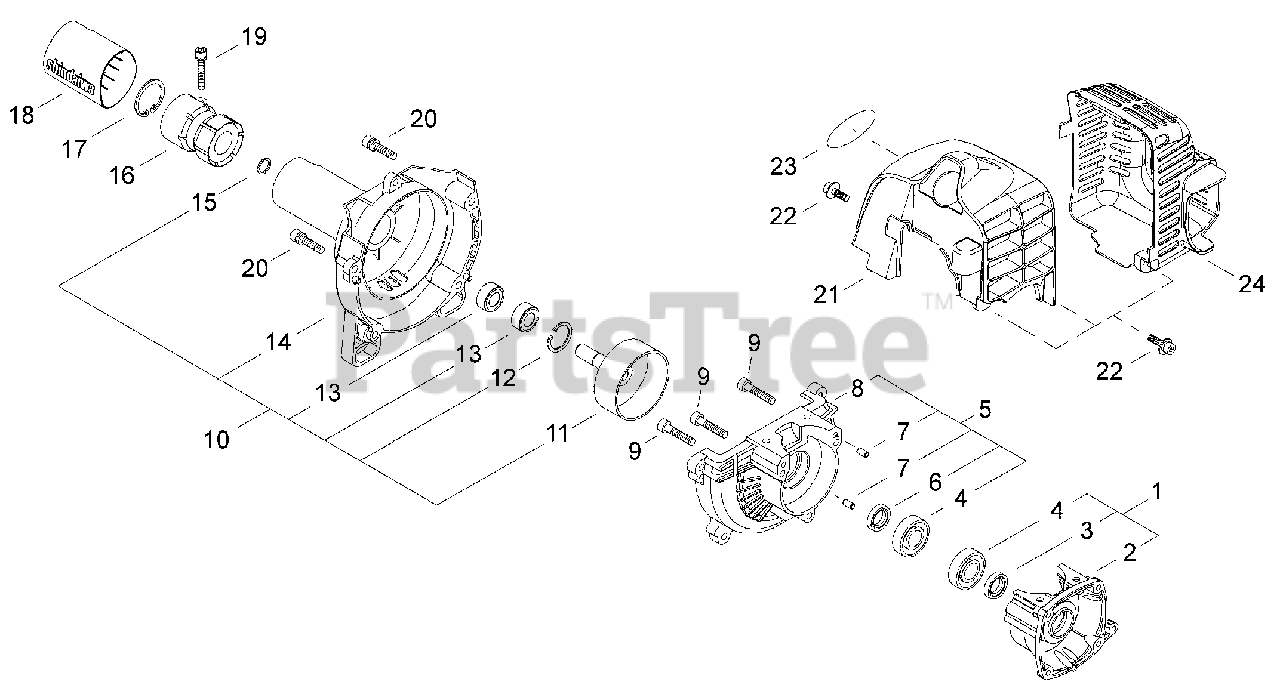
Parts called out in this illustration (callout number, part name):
2	CRANKCASE - REAR
2-1	CRANKCASE ASSY - REAR
3	SEAL, OIL - 12
4	BEARING, BALL - 6001C3
5	CRANKCASE ASSY - FRONT
6	SEAL, OIL - 12
7	PIN - LOCATING
8	CRANKCASE - FRONT
9	SCREW - 5X25
10	FAN CASE ASSY
11	DRUM, CLUTCH
12	RING, RETAINING - 26
13	BEARING, BALL - 6000DDU
14	COVER, FAN
15	RING, RETAINING
16	CUSHION
17	RING, RETAINING - 40
18	PROTECTOR
19	SCREW - 5X22
20	SCREW - 5X18
21	COVER, ENGINE
22	SCREW - 4X16
23	LABEL - MODEL 242
24	COVER, EXHAUST
